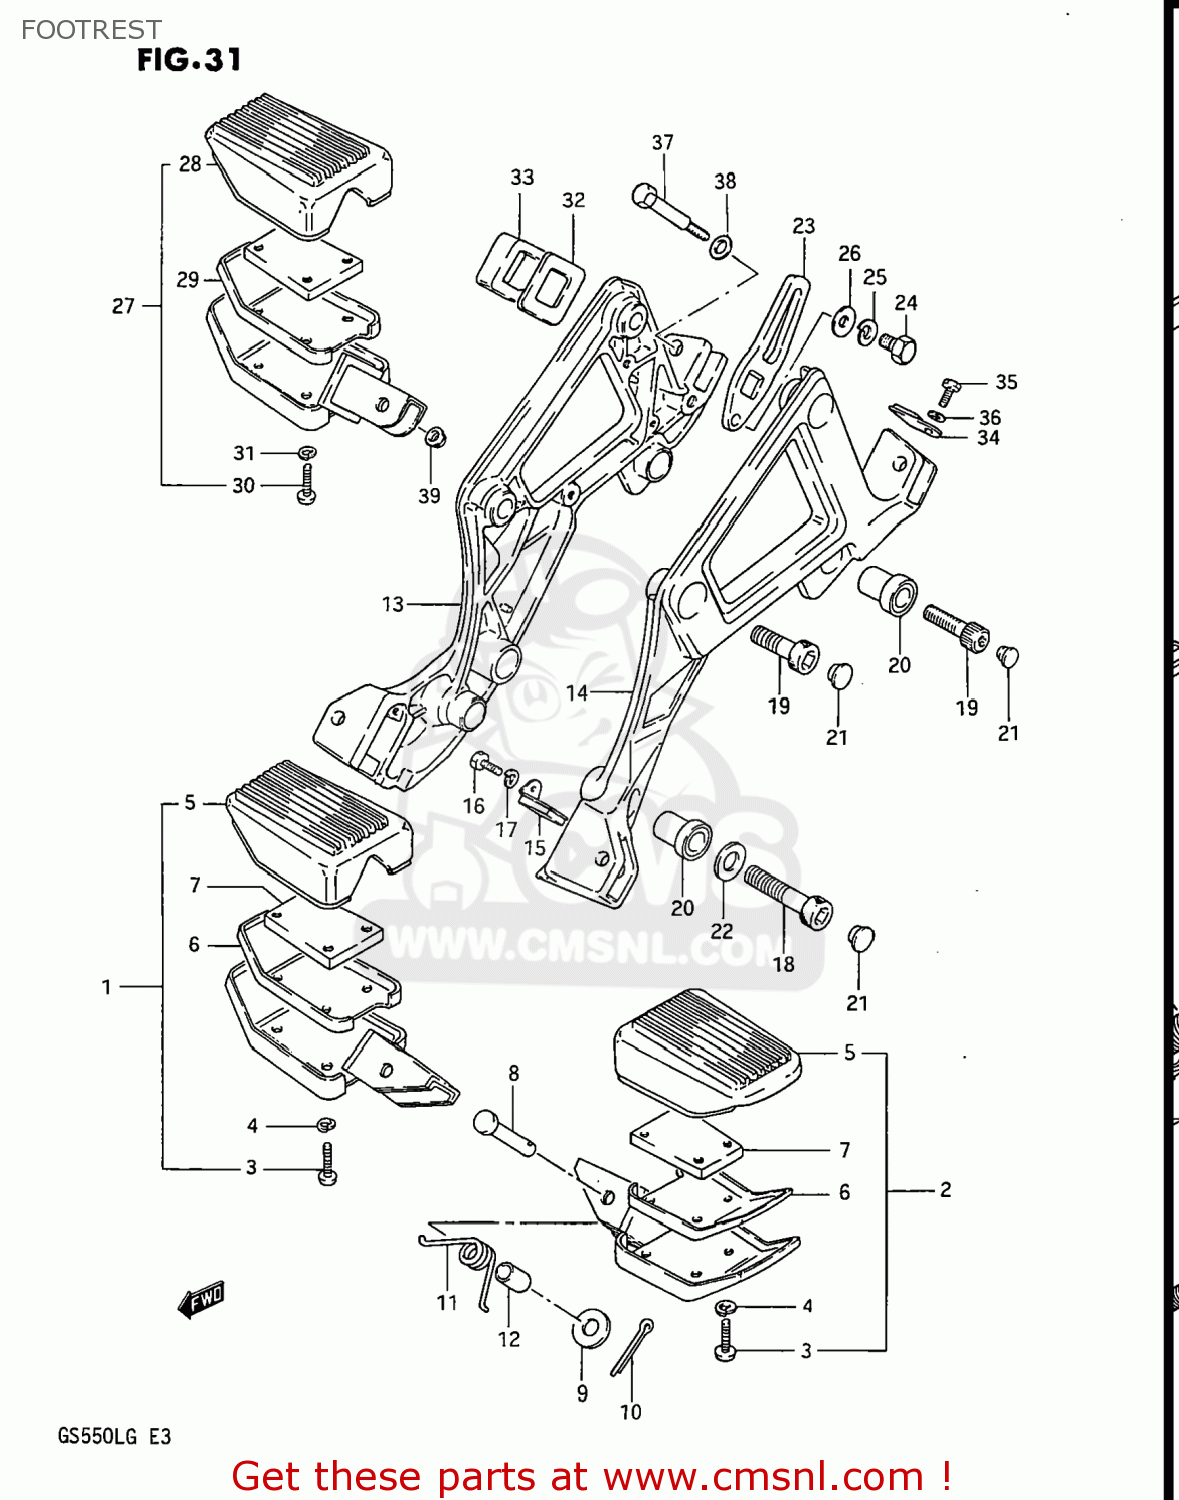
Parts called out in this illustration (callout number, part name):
1	FOOTREST ASSEMBLY,FRONT,RIGHT
2	FOOTREST ASSEMBLY,FRONT,LEFT
3	SCREW
4	LOCK WASHER
5	RUBBER,FRONT FOOTREST
6	PLATE, FOOTREST RUBBER
7	PLATE,FOOTREST RUBBER
8	PIN
9	WASHER
10	PIN 20X20
11	SPRING
12	BUSHING
13	BRACKET,MUFFLER,RIGHT
14	BRACKET,MUFFLER,LEFT
15	CUSHION,FRONT FOOTREST
16	BOLT 5X10
17	LOCK WASHER
18	BOLT
19	BOLT 10X27
20	BUSHING
21	CAP
22	WASHER
23	GUARD,REAR FOOT
24	BOLT,8X16
25	LOCK WASHER
26	WASHER
27	FOOTREST ASSEMBLY,REAR,LEFT
28	RUBBER,FRONT FOOTREST
30	SCREW
31	LOCK WASHER
32	WASHER,FOOTREST RUBBER
33	CUSHION,REAR FOOTREST
34	CUSHION,REAR FOOTREST
35	BOLT 5X10
36	LOCK WASHER
37	BOLT
38	WASHER
39	NUT
